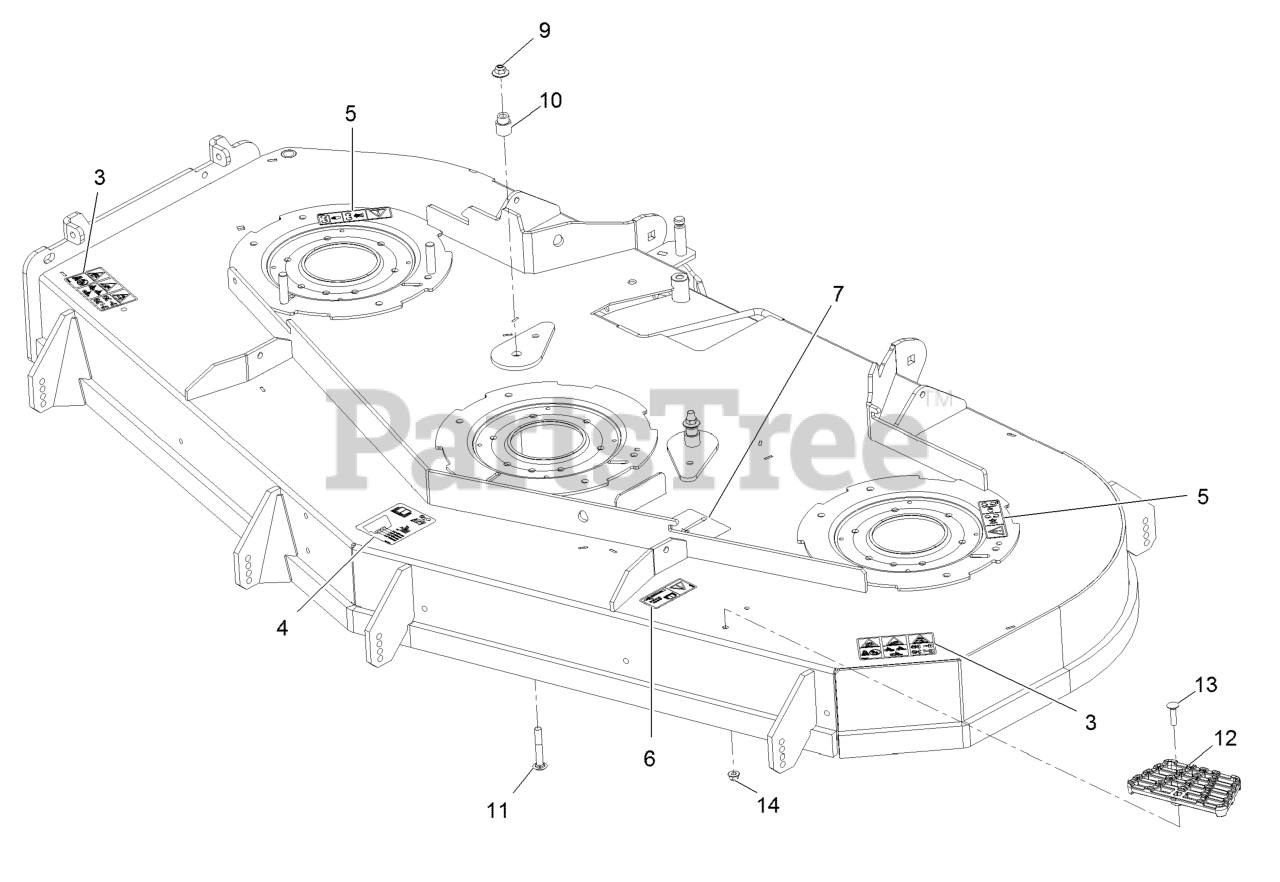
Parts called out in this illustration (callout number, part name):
3	DECAL-DANGER THROWN OBJECTS
4	DECAL-ROLLER, ANTI-SCALP
5	DECAL-COVER, MISSING
6	DECAL-BOLT TORQUE
7	DECAL-BELT ROUTING
9	Nut-Nyloc 3/8-16 Flg
10	BUSHING-IDLER
11	SCREW-CARR
12	STEP-DECK
13	Bolt-Carriage 5/16-18 X 1 1/4
14	NUT-HF, NI
